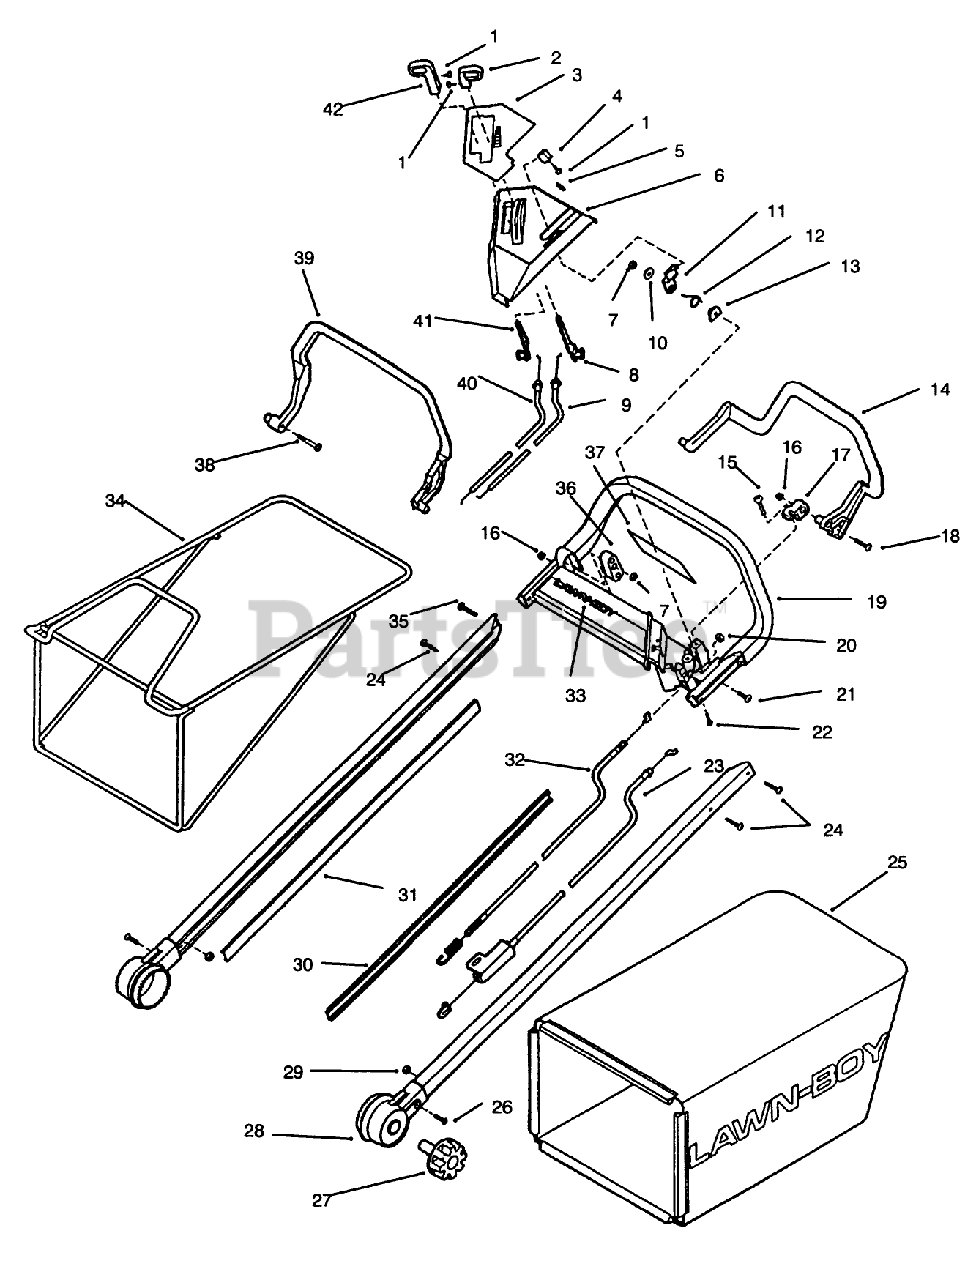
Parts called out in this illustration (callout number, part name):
6	COVER-CNTRL UPPER
7	NUT-LOCK, NI
11	BBC LATCH LB
14	BAIL-S.P. *
16	LOCKNUT FLAN
17	PIVOT BAIL PL
21	SCREW-CROSS RECESS
23	CABLE AY WESC
25	REPL BAG FOR 684190
27	KNOB-HDLE MT.ASM*B
28	HANDLE SHAFT AY
29	LOCKNUT FLAN
30	INSERT - HANDLE
32	CABLE AY
35	SCREW-TRUSS
36	BLOCK BAIL PL
40	CABLE AY. WESCON
42	KNOB & SCREW AY
